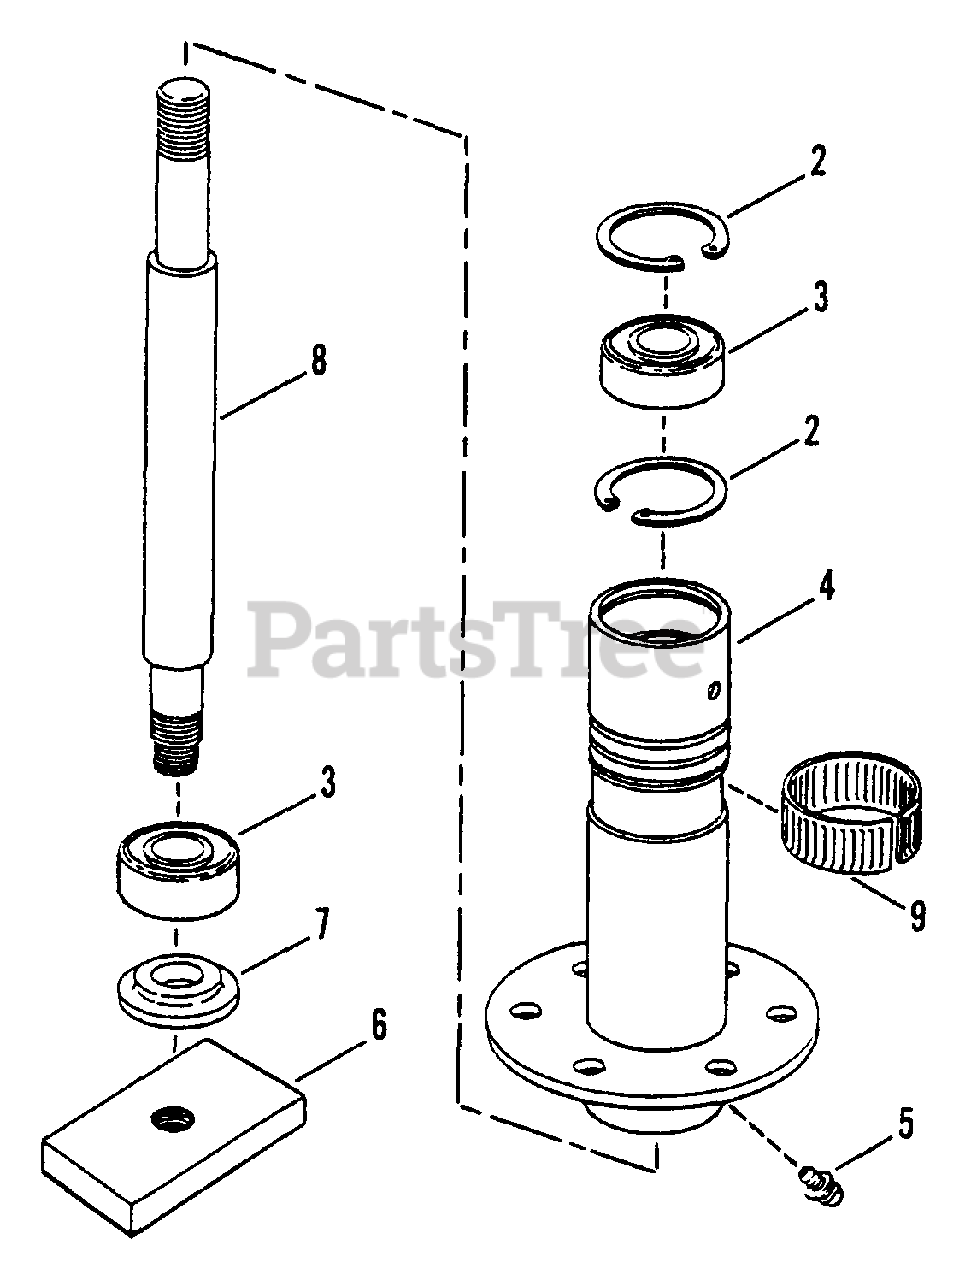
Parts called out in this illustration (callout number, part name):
1	ASSEMBLY, Spindle Housing
2	RING, Retaining
3	BEARING, Spindle
4	HOUSING, Spindle
5	FITTING, Lube (Press fit for .187 hole-no ball)
6	HOLDER, Blade
7	WASHER, Spindle
8	SPINDLE 9.50" Long
9	RING, Tolerance
